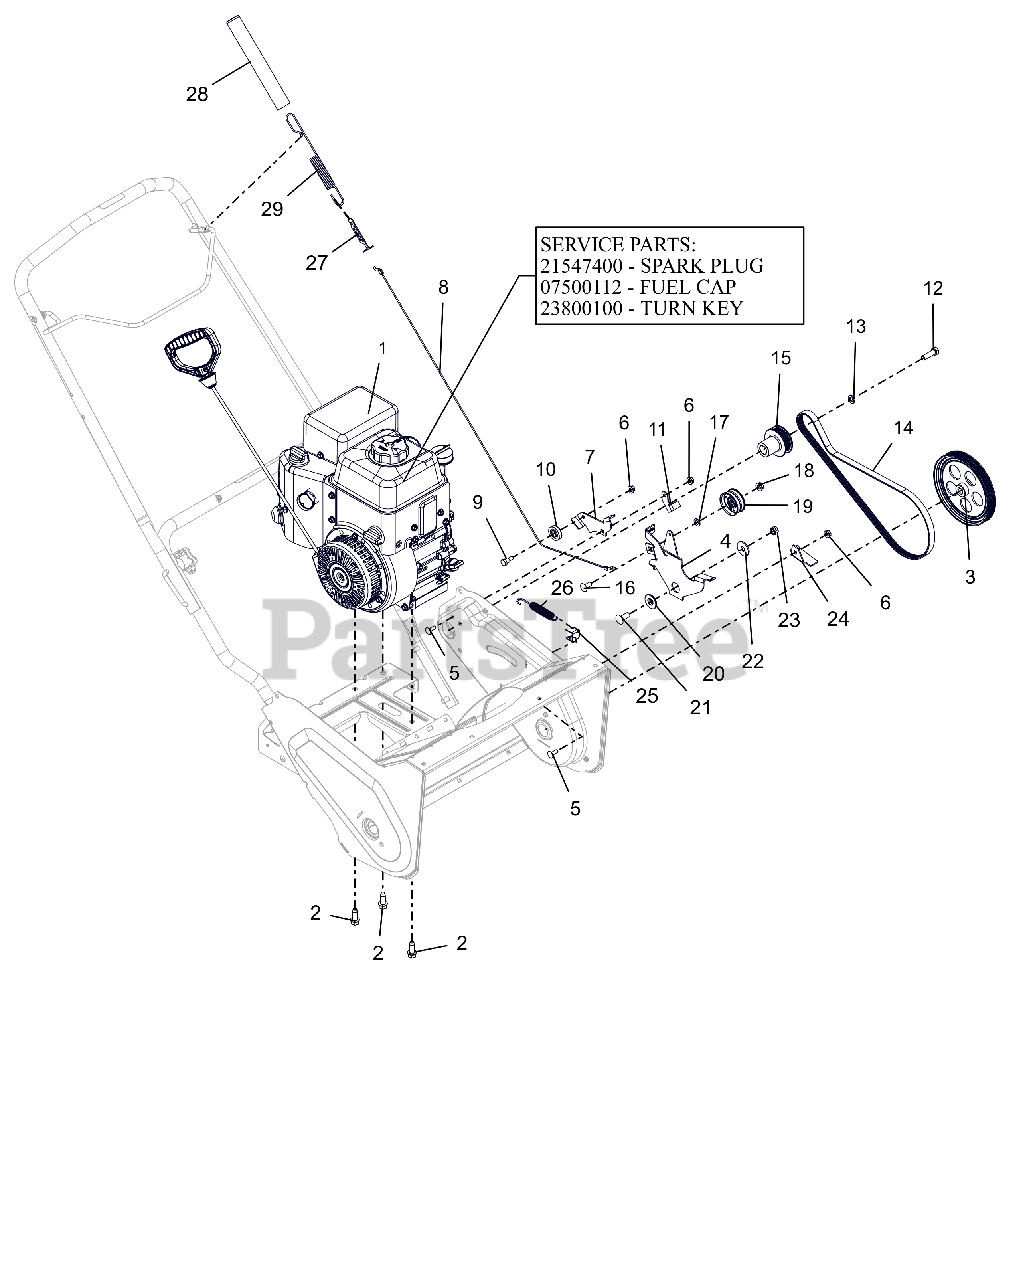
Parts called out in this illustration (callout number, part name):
1	ENGINE, ARIENS AX208 RECOIL
1	PLUG, SPARK
1	CAP, FUEL TANK BLACK
1	KEY, TURN LCT (2/PACKAGE)
2	@SCR-TAP .38-16X1.00 HWH TR YZ
3	PULLEY, POLY V-BELT J-6 W/HUB
4	ARM, IDLER/BRAKE
5	@BLT-RDHDSQNK .25-20X.75 G5YZ
6	@NUT-LK-TOP-FLG .25-20 YWZC
7	BRKT, CABLE PULLEY
8	CABLE, AUGER
9	BOLT, SHLDR-.375X.375X.25-20
10	PULLEY, CABLE
11	FINGER, BELT
12	BLT-HEX .375-24X1.25 GR5 YWZC
13	@WSHR-LK .38X.094 REG YWZC
14	POLY V-BELT, J-6 RIBS
15	SHEAVE, ENGINE - 6J
16	@BLT-RHDSSQNK .31-18X.75 G5YZ
17	WSHR-FL-STL .323X.625X.062 YWZ
18	@NUT-LK-CTR-FLG .31-18 YZ GR F
19	IDLER, FLAT - 1.875"
20	BSHG-FLG .555X.860X.220X1.250
21	@BLT-RDHDSQNK .38-16X1.00 G5YZ
22	@WSHR-FL-STL .406X1.25X.10 ZC
23	@NUT-LK-CTR .38-16 YWZC
24	FINGER, BELT
25	BRKT, SPRG
26	SPRING, EXTENSION-SWIVEL
27	PLATE, CABLE ADJUSTMENT
28	COVER, CABLE SPRING
29	SPRG, EXT .100X.740X8.175
